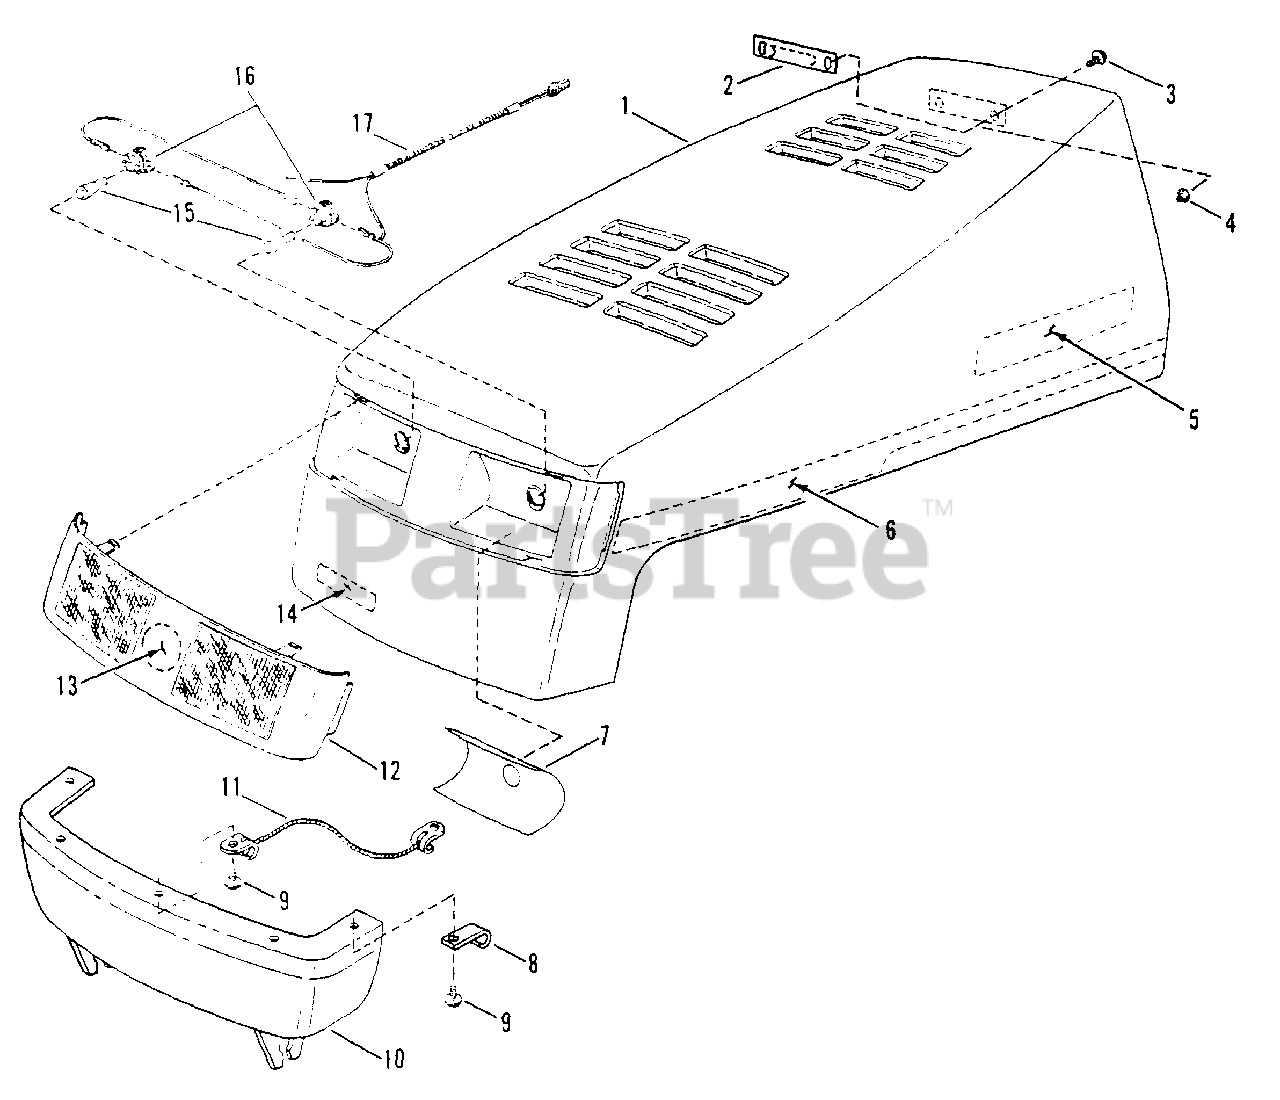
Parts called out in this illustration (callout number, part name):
1	HOOD
2	LATCH, Spring
3	SCREW, 1/4-20 X 5/8" Truss Head, Torx
4	NUT, 1/4-20 Hex Nyloc
5	DECAL-SNAPPER, 8" Molded Logo, White Letters
5	DECAL-SNAPPER, 8" Molded Logo, Silver Letters
6	DECAL, Hood Right Side
6	DECAL, Hood Left Side
7	DECAL, Lens, Left Side
8	CLIP "J"
9	SCREW, M4.8 X 1.59 X 16.00MM Special
10	BUMPER, Front
11	LANYARD, Hood
12	LENS, Solid Black (33" Model)
12	LENS, Clear
13	DECAL, Molded Medallion, Convertible Mower
14	DECAL, SNAPPER, 4" Molded Logo, White Letters
14	DECAL, SNAPPER, 4" Molded Logo, Teal Letters
15	BULB, Headlights
16	SOCKET, Headlight Bulb
17	HARNESS, Headlight Warning
